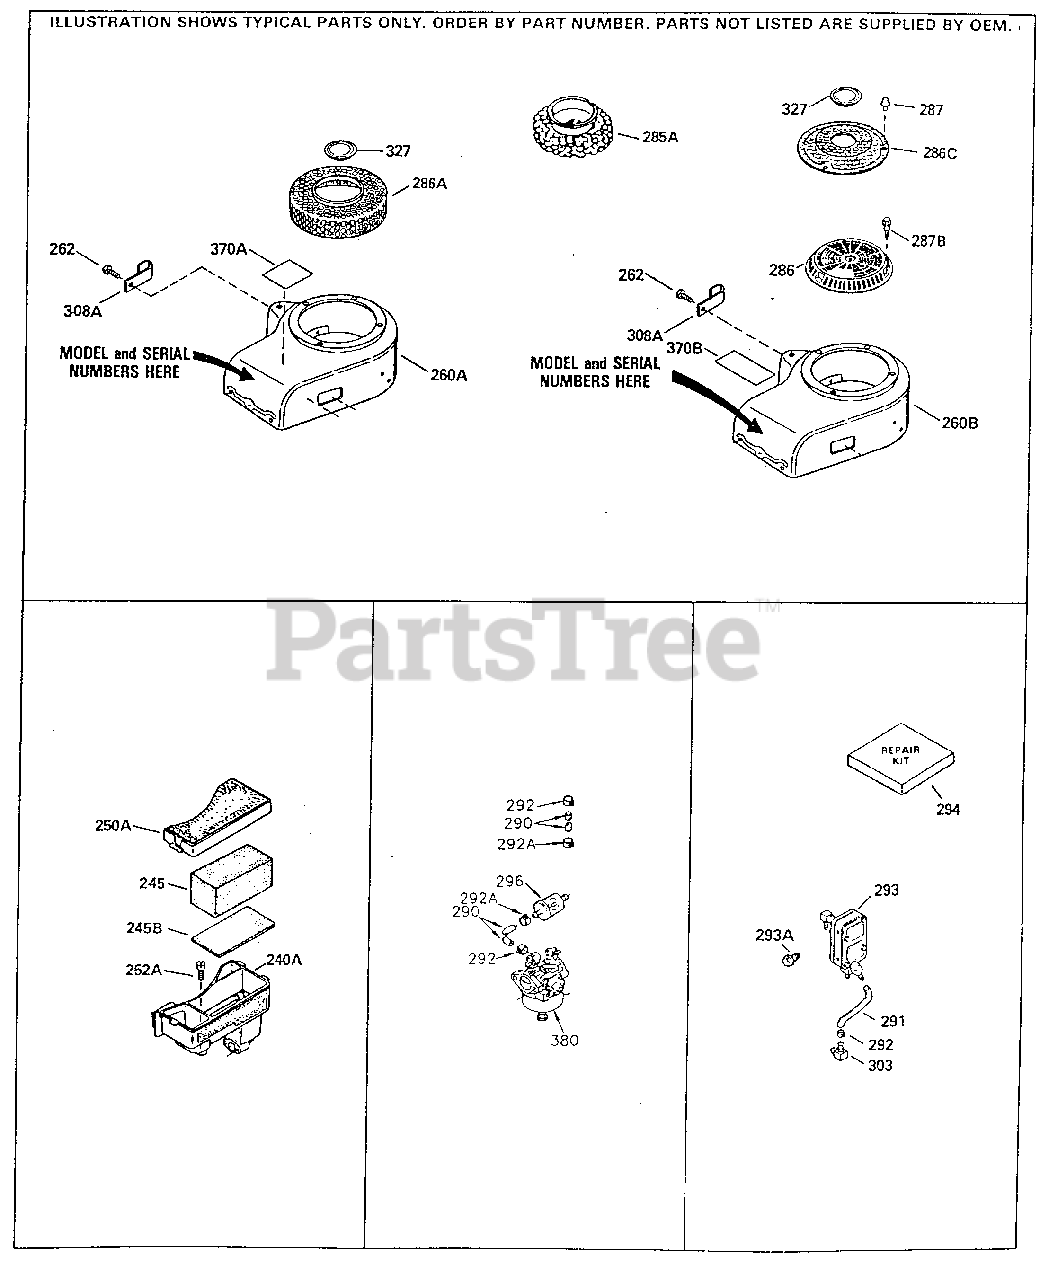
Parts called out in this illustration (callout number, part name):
245	Air Filter (Incl. 234) also available in Packaged Part #740015B
260B	Blower Housing
262	Screw, T-40, 5/16-24 x 21/32"
286	Starter Screen
287B	Screw, 10-32 x 13/32"
290	Fuel Line (16" or 40cm)
292	Fuel Line Clamp
292A	Fuel Line Clamp
296	Fuel Filter (Incl. 292) (also availab le as Packaged Part #740003B) 2A)
308A	Fill Tube Clip
370A	Name Decal
380	Carburetor (Incl. 184) (Refer to Divi sion 5, Section A, page A4-8 or Fiche 12, Grid F-7for breakdown)
